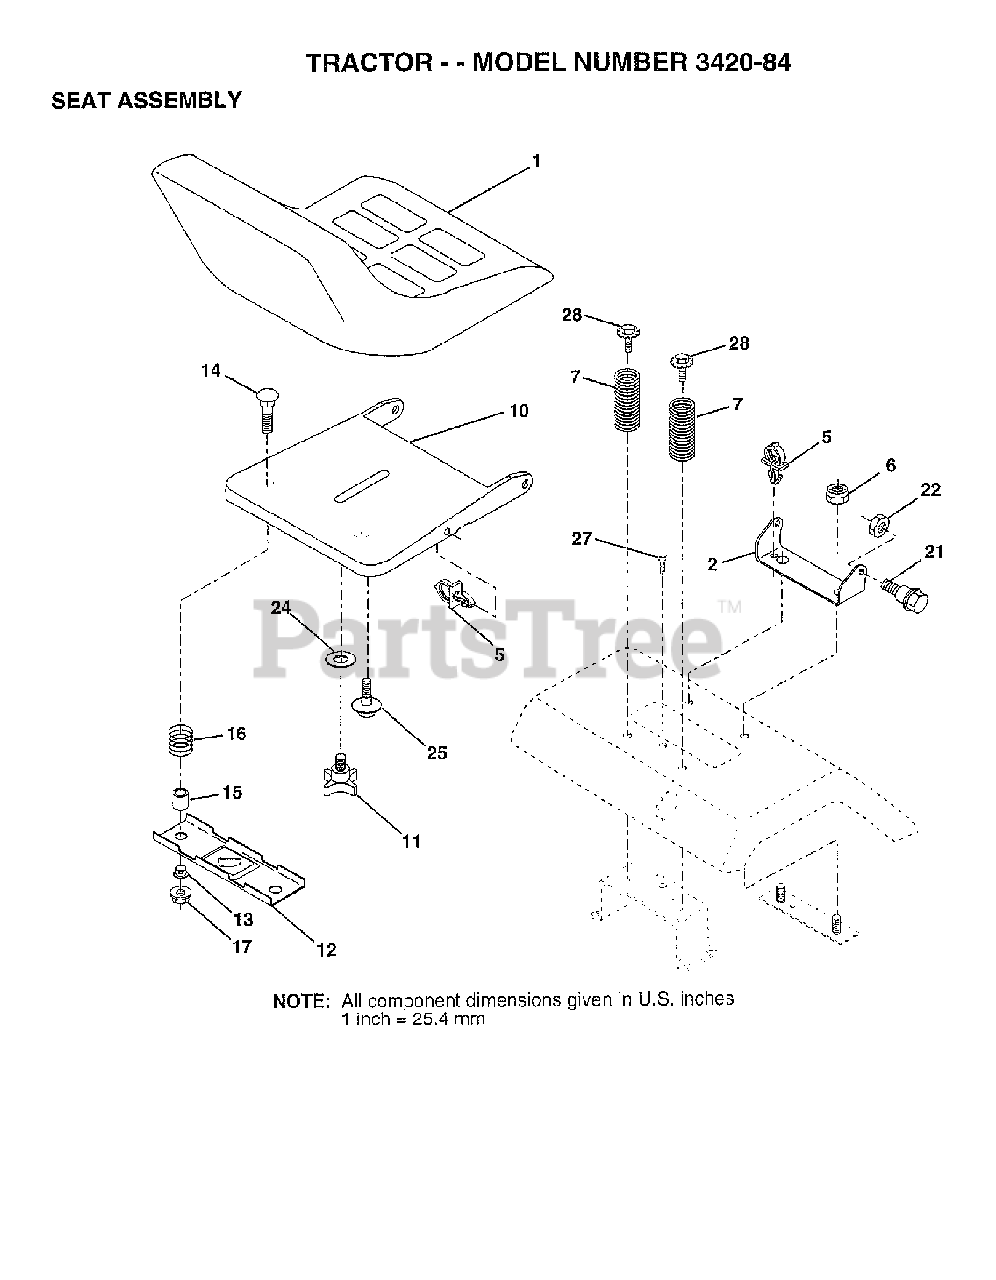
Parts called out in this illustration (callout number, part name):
2	BRKT,SEAT PIVOT**
5	PUSH CLIP
6	NUT
7	SPRING COMPRESSION
12	BRKT SWITCH
14	BOLT.ROUND.HEAD.SQUARE.NECK
15	SPACER SPLIT
16	SPRING COMPRESSED
17	NUT T
22	LOCKNUT
25	BOLT, SHOULDER**
27	SCREW LT
